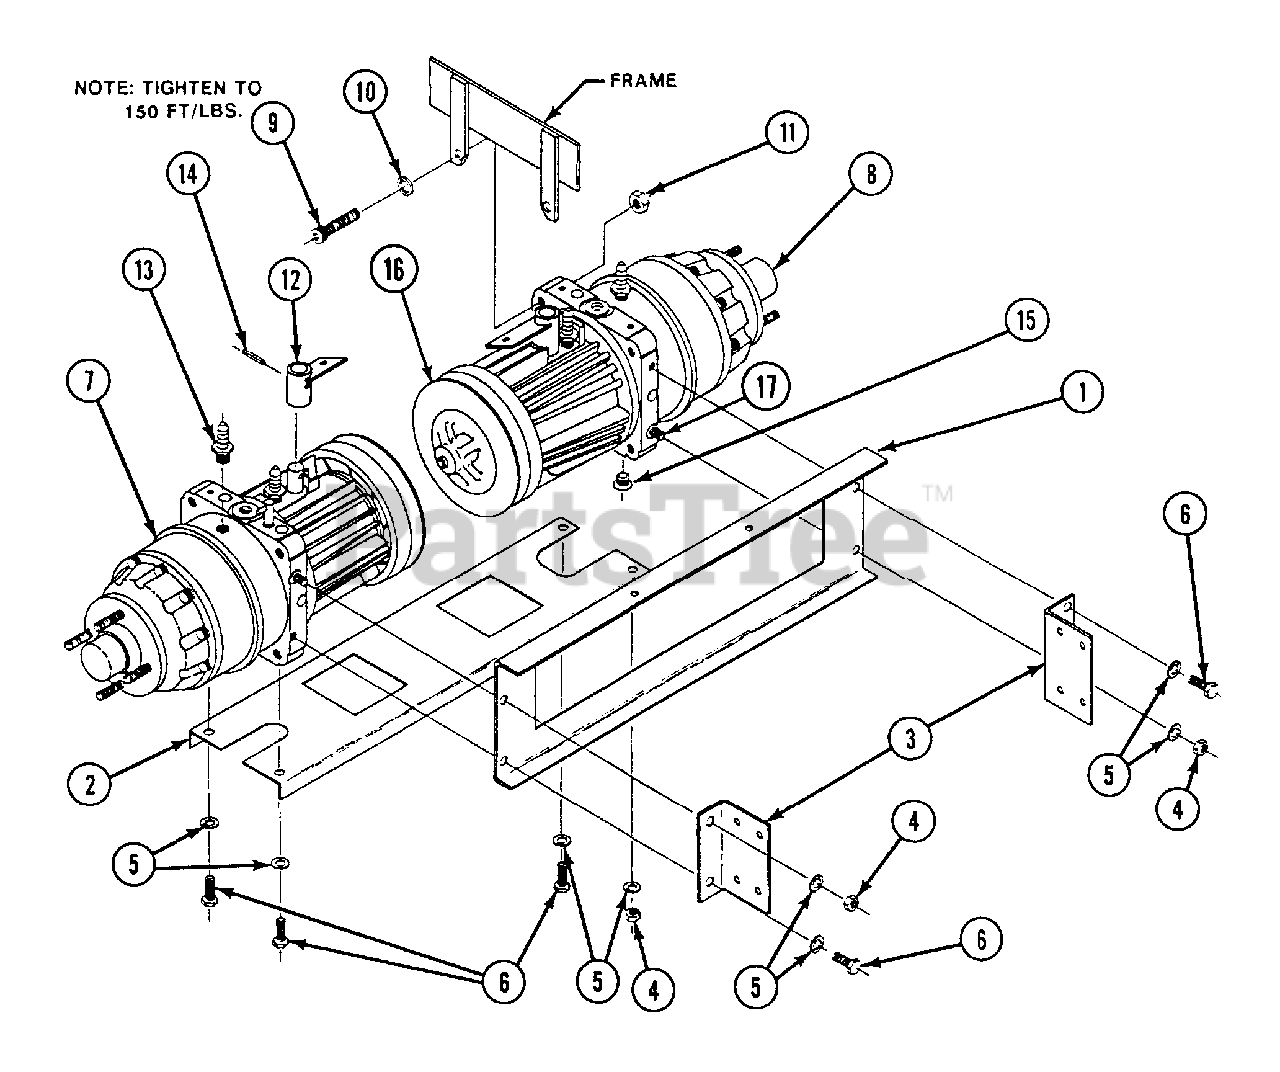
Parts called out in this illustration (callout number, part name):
1	FRONT CROSS MEMBER
2	BOTTOM CROSS MEMBER
3	DRAG BAR MOUNT
4	NUT, HEX: 1/2-13
5	LOCKWASHER, SPLT SPRNG: 1/2
6	CAPSCREW, HX HD: 1/2-13 X 1-1/4
7	UNISTAT ASSEMBLY, RH
8	UNISTAT ASSEMBLY, LH
9	CAPSCREW, SKT HD: 5/8-11 X 2-1/4
10	LOCKWASHER, SPLT SPRNG: 5/8
11	NUT, HEX JAM: 5/8-11
12	SHIFT LEVER WELDMENT, RH (SHOWN REMOVED)
13	HOSE BARB, UNISTAT
14	ROLL PIN: 5/16 X 1-1/4
15	PLUG, 3/4-16 W/ 0-RING
16	PULLEY
17	FASTENER
